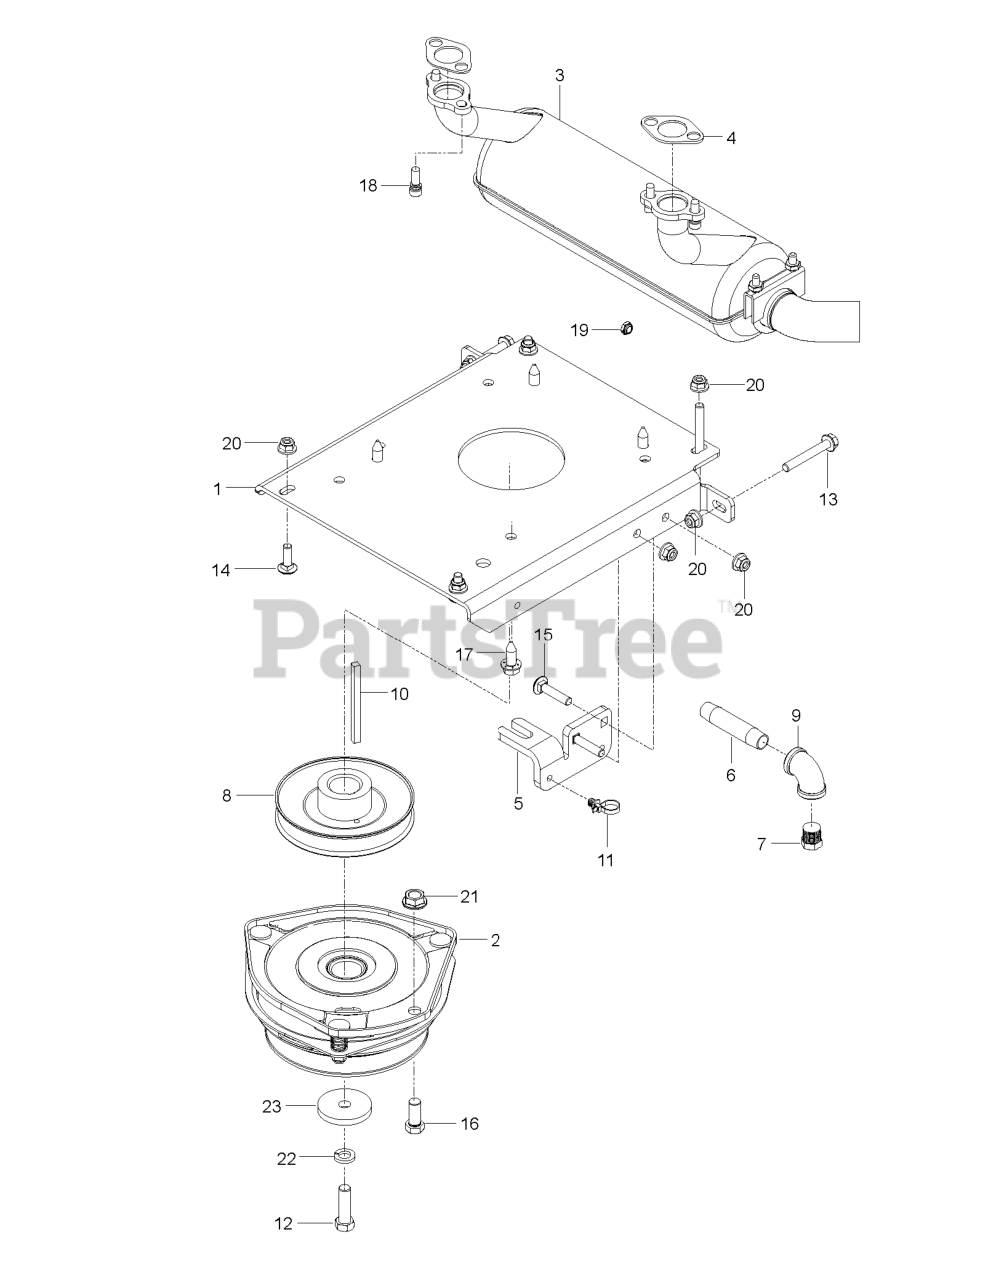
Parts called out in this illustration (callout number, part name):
1	PLATE.ENGINE.BLACK
2	CLUTCH, GT3.5
3	MUFFLER, B&S CYCLONIC
4	GASKET.MUFFLER.B&S.REF #273485
5	STOP, CLUTCH, OGURA
6	PIPE NIPPLE 3/8 X 3
7	PLUG, DRAIN 3/8 NPTF
8	PULLEY, ENGINE
9	90 DEG.ELBOW 3/8NPT
10	KEY, 1/4 SQ X 3.5
11	TIE WRAP, 8-3/8", W/CLIP
12	CLUTCH BOLT7/16-20X1.5GR5.96HR
13	HHFS 5/16-18 X 2.25 GD 5
14	RHSNB 5/16C X 1
15	RHSNB 5/16-18 X 1-1/2 GR 5 ZD
16	BOLT FIN HEX 7/16-14 X 1
17	SCREW 3/8-16X1
18	SCREW.SOCKET.HEAD.5/16-18
19	JAM NUT 1/4C (2 2 PW01)
20	5/16-18 NYLOC FLANGE NUT
21	NUT 7/16C WHIZ
22	WASHER 7/16 LOCK
23	BLADE WASHER
